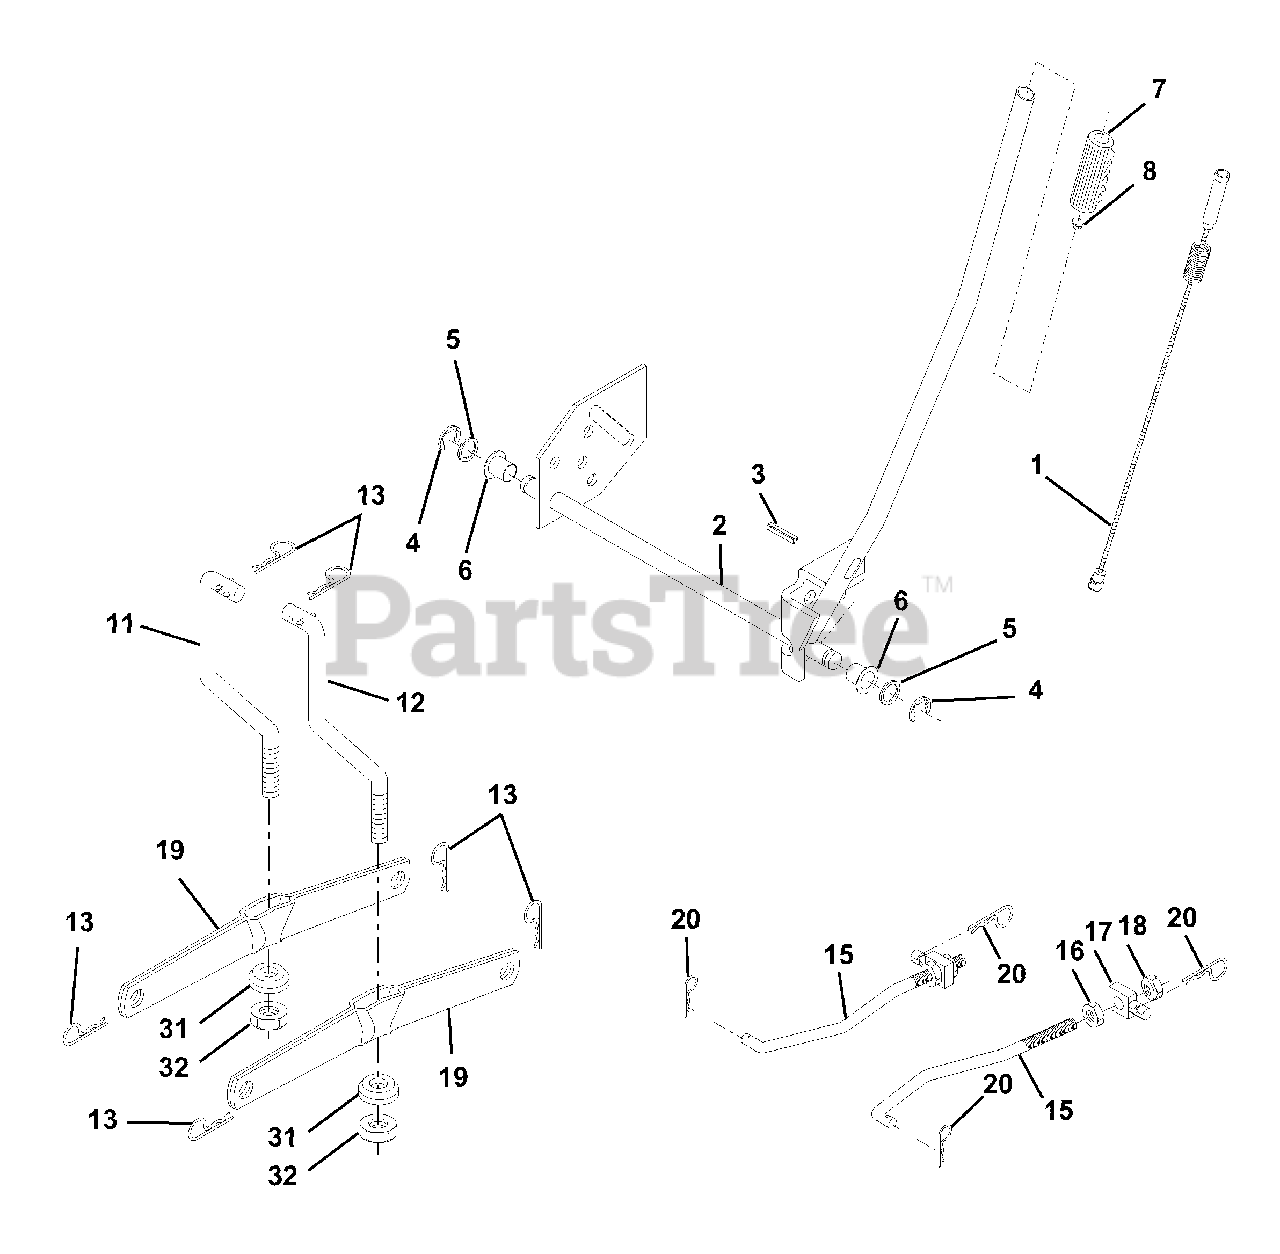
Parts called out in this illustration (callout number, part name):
1	Wire Asm Inner/Sprg w/Plunger
2	Shaft Asm Lift
3	Pin Groove
4	E Ring #5133-62
5	Washer 21/32 x 1 x 21 Ga.
6	Bearing Nylon
7	Grip Handle
8	Button Plunger
11	Link Lift Lh
12	Link Lift Rh
13	Retainer Spring
15	Link Front
16	Nut Jam Hex 1/2-13 Unc
17	Trunnion Blk Zinc
18	Nut Lock w/Wsh 1/2-13 Unc
19	Arm Suspension Rear
20	Retainer Spring
31	Bearing Pvt Lift Spherical
32	Nut Crownlock 3/8-24
